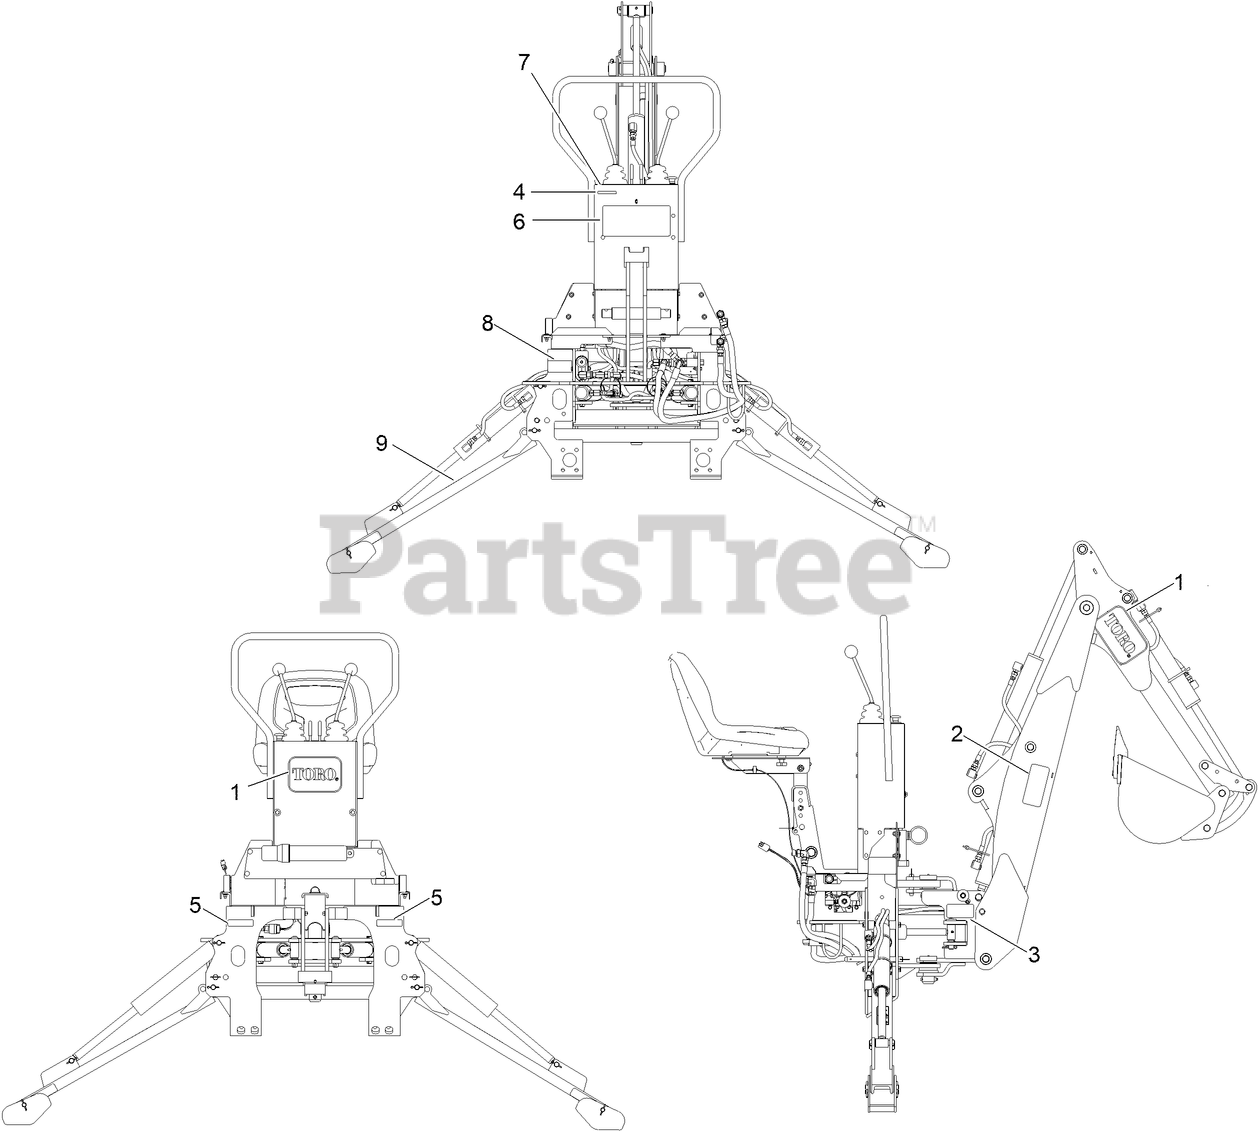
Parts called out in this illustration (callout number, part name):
1	DECAL
2	DECAL-WARNING
3	DECAL-PLACEMENT, PIN
4	DECAL-WARNING
5	DECAL-POINT, PINCH
6	DECAL-WARNING, BACK HOE
7	DECAL-OPERATION, BACK HOE
8	PLATE-SERIAL
9	DECAL-WARNING, CRUSHING
